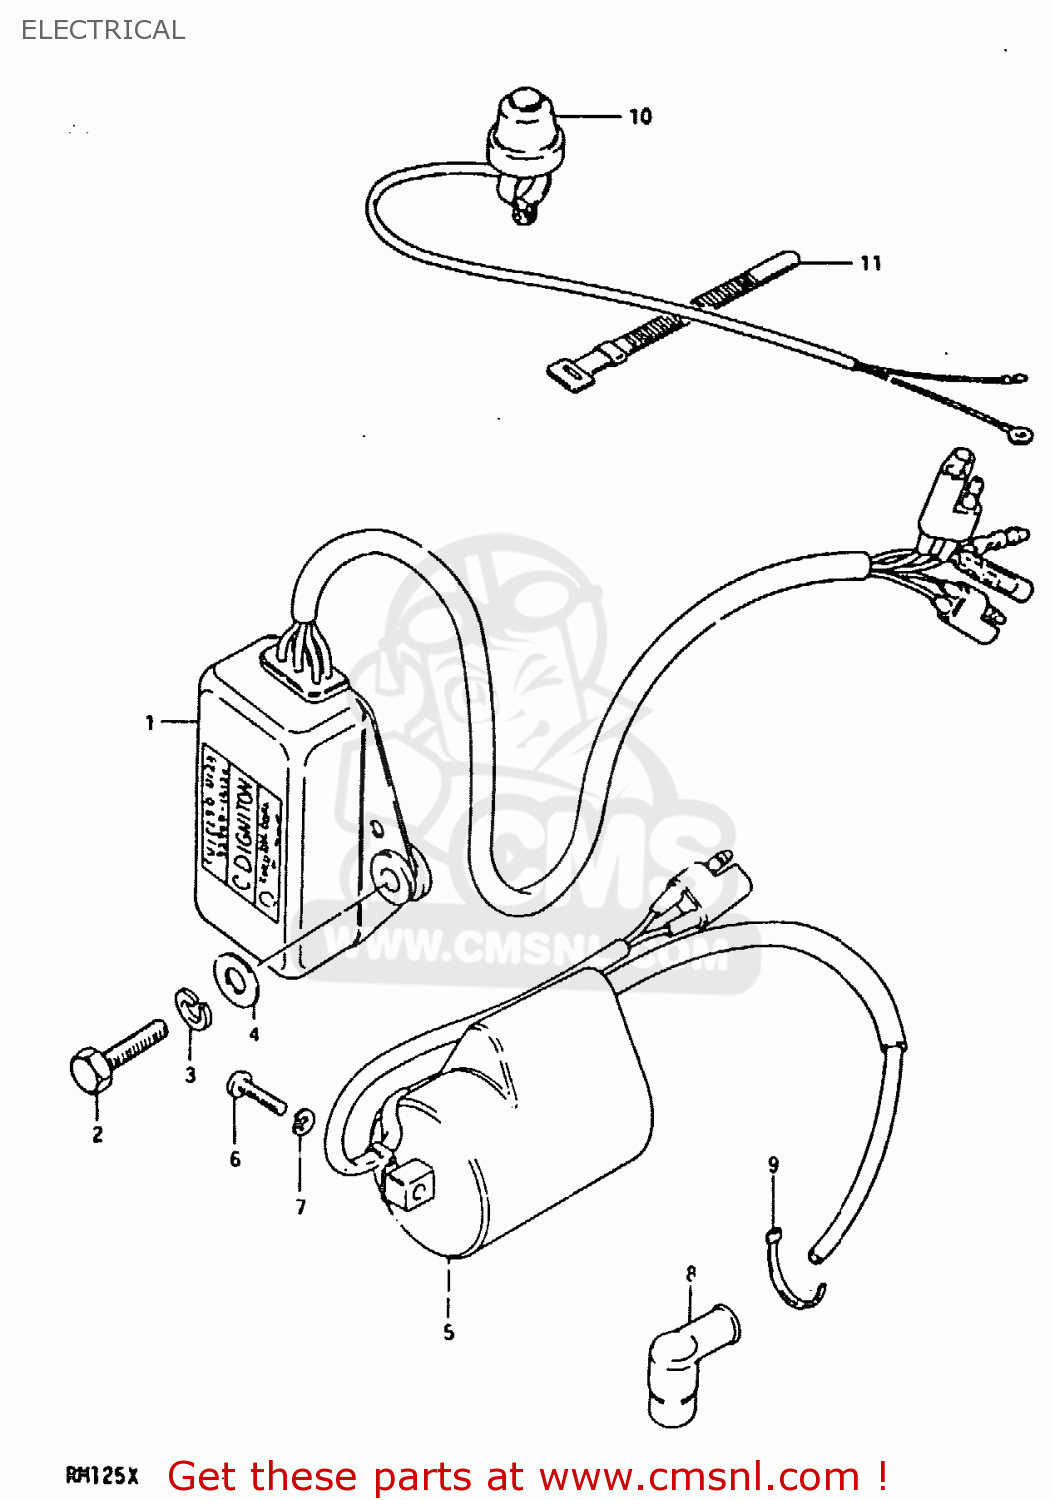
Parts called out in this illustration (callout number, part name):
1	CDI UNIT
2	BOLT
3	LOCK WASHER
4	WASHER(6.5X16X1.2)
5	COIL ASSY,IGNITION
6	SCREW 5X20
7	LOCK WASHER
8	CAP,SPARK PLUG
9	CLAMP
10	SWITCH ASSEMBLY
11	CLAMP(L:120)
